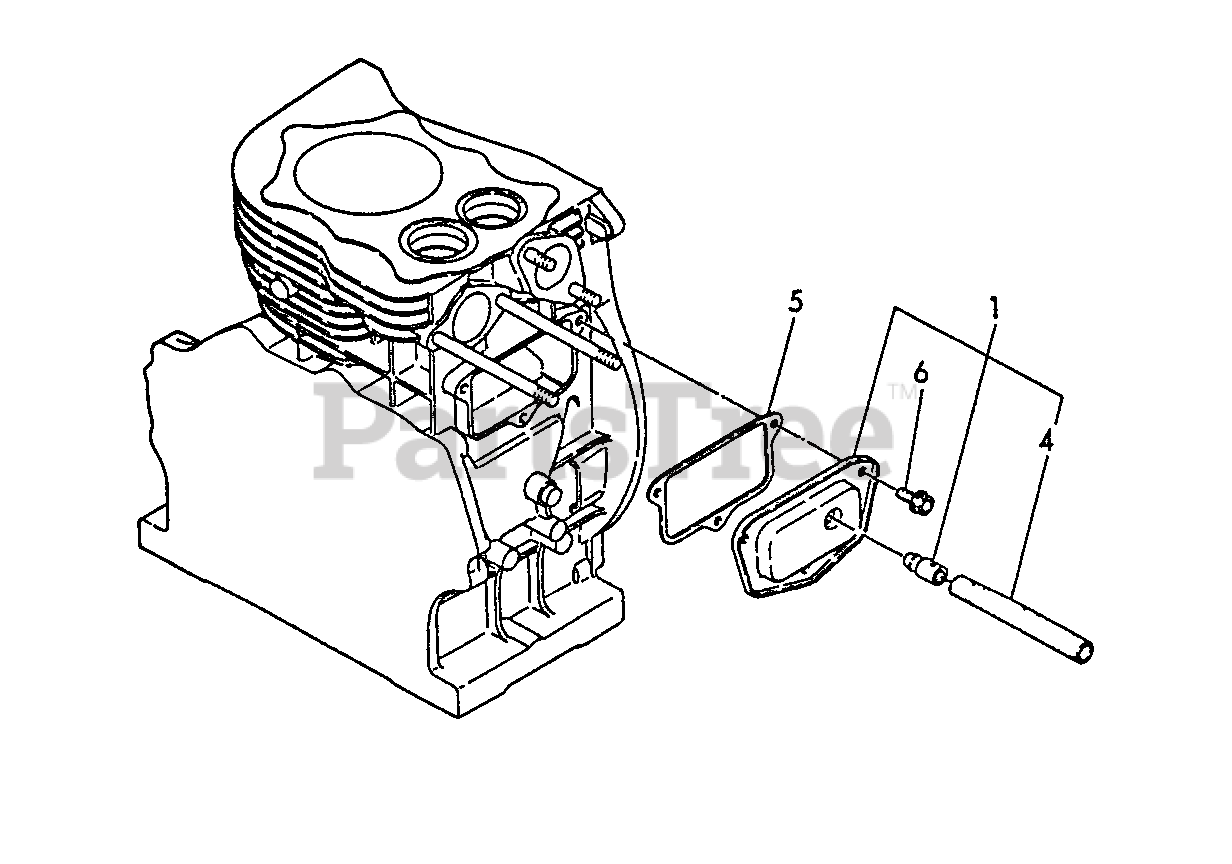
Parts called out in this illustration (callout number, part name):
1	VENT, FUEL TANK
4	PIPE - BREATHER
5	GASKET, BREATHER
6	BOLT - 6X8 -- PLATED
